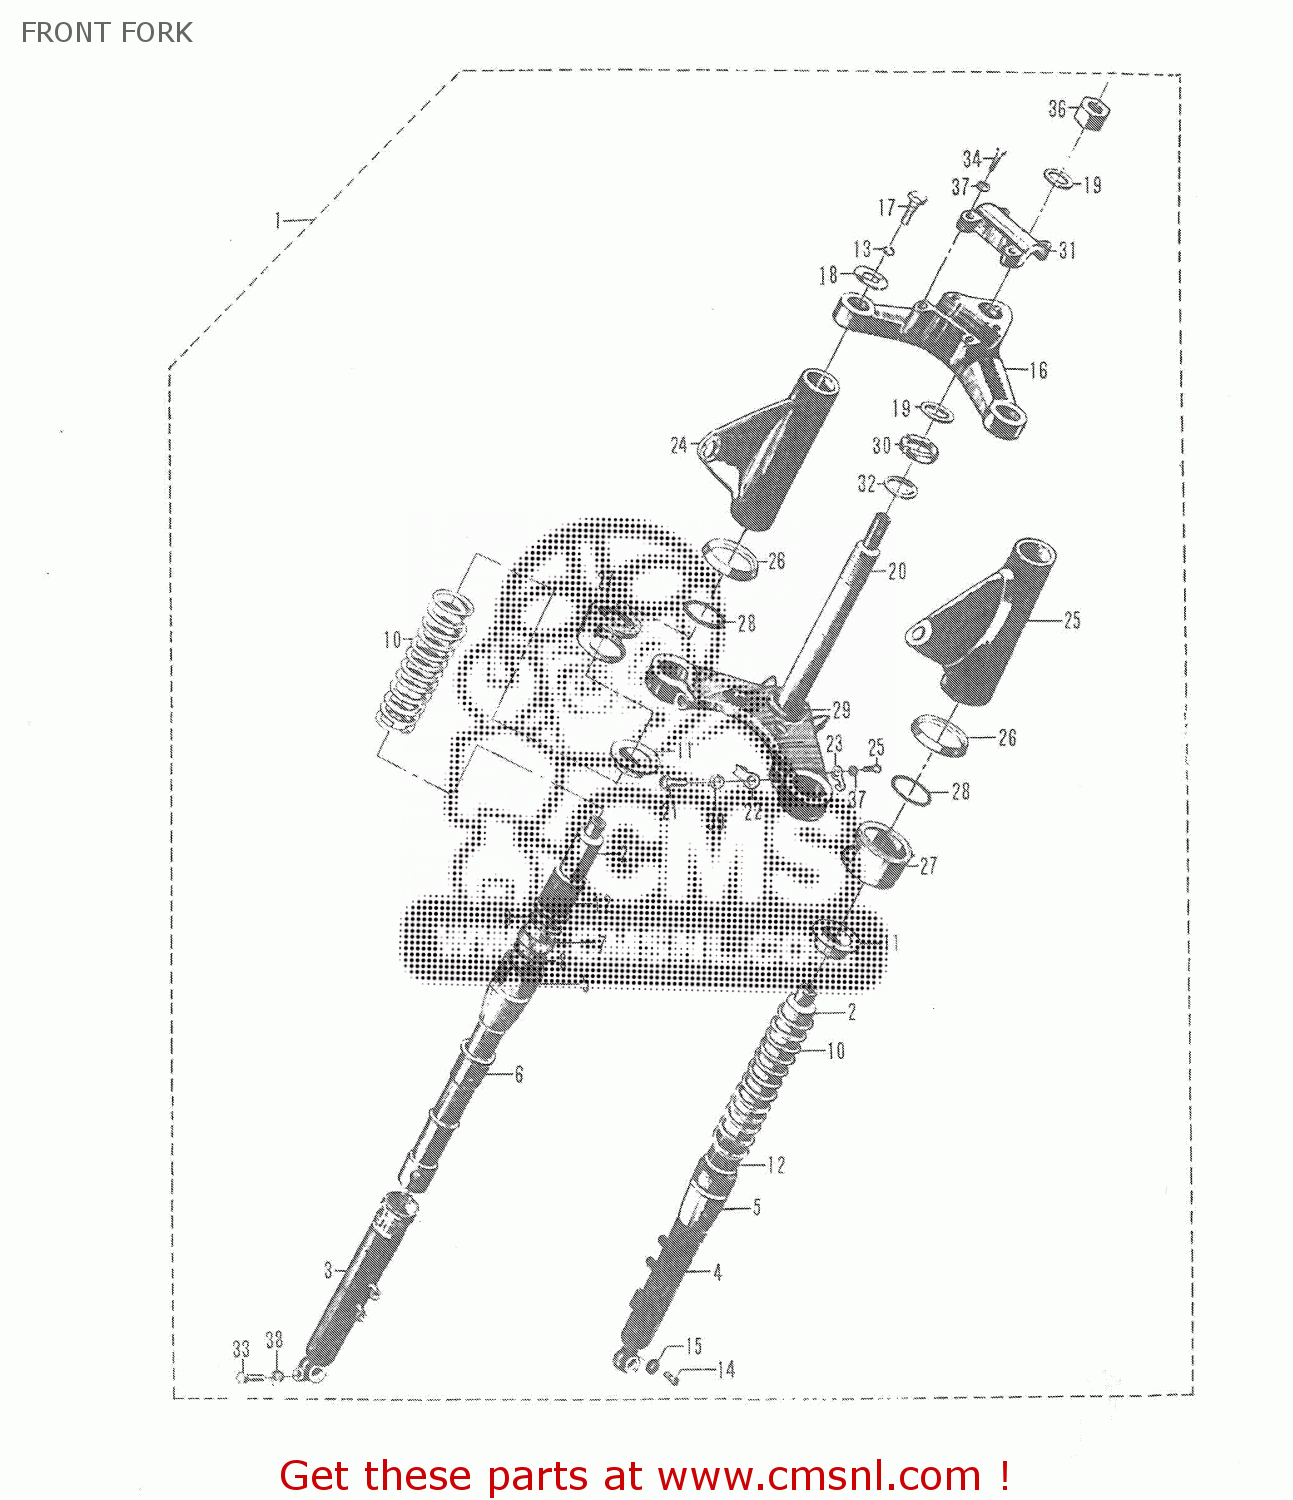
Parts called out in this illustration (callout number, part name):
1	FRONT FORK ASS'Y
2	TUBE,FORK,INNER
3	FRONT RIGHT OUTER TUBE
4	FRONT LEFT OUTER TUBE
5	FORK OUTER TUBE NUT
6	BUSHING,GUIDE
7	OIL SEAL,FRONT FORK
8	O-RING,FORK OIL SEAL L
9	WASHER
10	SPRING,FRONT FORK
11	GUIDE,SPRING
12	DUST SEAL,FRONT FORK
13	FORK FITTING BOLT "O" RING
14	FORK DRAIN PLUG
15	GASKET,DRAIN,PLUG (NAS)
16	STEERING STEM HEAD
17	FORK FITTING BOLT
18	WASHER
19	WASHER
20	STEERING STEM
21	FORK INNER TUBE FITTING BOLT
22	CLIP,SPEEDOMETER CABLE
23	CLIP,BRAKE CABLE
24	HEAD LAMP RIGHT BRACKET
25	HEAD LAMP LEFT BRACKET
26	SEAT,HEADLAMP BRACKET
27	PROTECTOR,OUTER TUBE,LEFT
28	CUSHION,HEADLAMP BRACKET
29	RACE,STEERING,OUTER,UPPER
30	NUT,STEERING STEM
31	CLAMP,HANDLEBAR
32	WASHER
33	SMALL HEAD HEXAGON BOLT
34	CROWN HEAD BOLT
35	CROSS HEAD SCREW
36	SMALL HEXAGON NUT
37	LOCK WASHER
38	LOCK WASHER
39	LOCK WASHER
